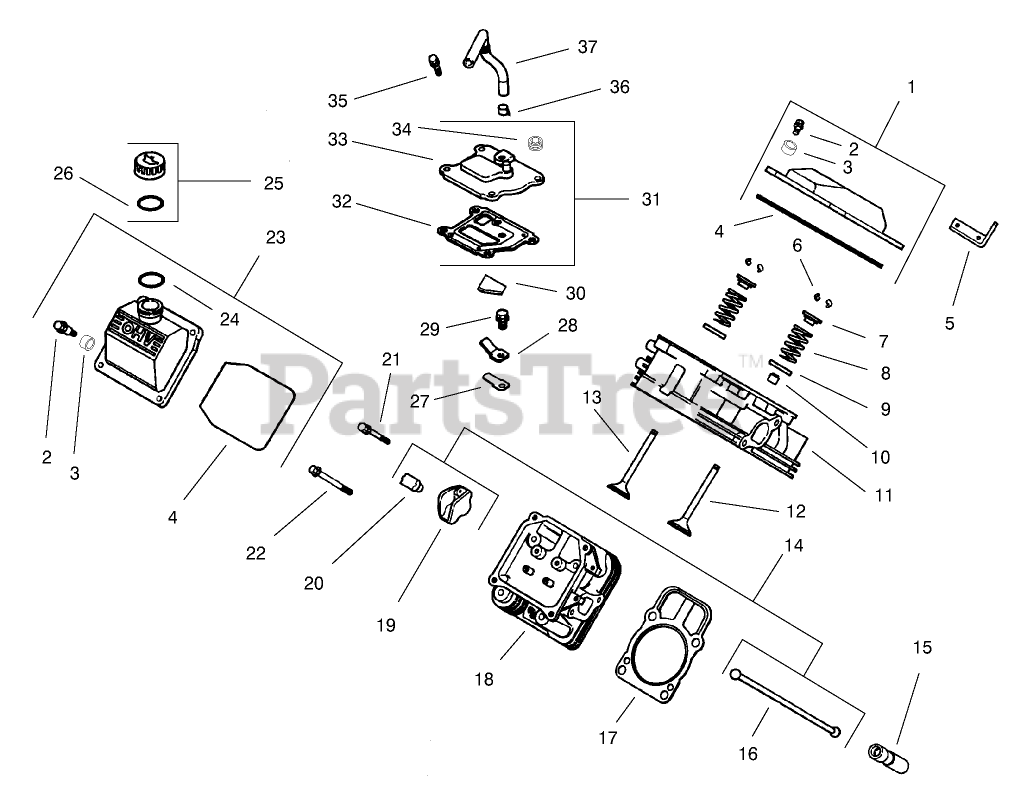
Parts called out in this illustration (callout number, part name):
1	Kit-Valve cover, Plain (Includes 3-4)
2	SCREW-FLANGE (M6X1.0X30)
3	Spacer
4	O-Ring
5	STRAP-LIFTING
6	RETAINER KIT
7	CAP-SPRING, VALVE
8	SPRING-VALVE
9	RETAINER-SPRING
10	Seal-Stem, Valve
11	#1 Cylinder Head ASM
12	VALVE-INTAKE (STD)
13	VALVE-EXHAUST (STD)
14	Kit-Train, Valve (Includes 16, 19, 20)
15	Lifter-Valve
16	ROD-PUSH
17	Gasket-Head, Cylinder
18	#2 Cylinder Head ASM
19	ARM-ROCKER
20	Pivot-Arm, Rocker
21	SCREW-FLANGE (M6X1.0X34)
22	SCREW-FLANGE (M10X1.5X90)
23	Kit-Valve Cover, Oil Fill (Includes 2-4, 24)
24	O-Ring
25	Kit-Cap, Oil Fill (Includes 26)
26	O-Ring
27	REED-BREATHER
28	Retainer-Reed, Breather
29	SCREW-HHFTF (M5X.80X10)
30	Filter-Breather
31	Kit-Breather (Includes 32-34)
32	Gasket-Breather
33	Cover-Breather
34	Plug
35	SCREW-HHFTF (M6X1.0X20)
36	Clamp-Hose
37	Hose-Breather
